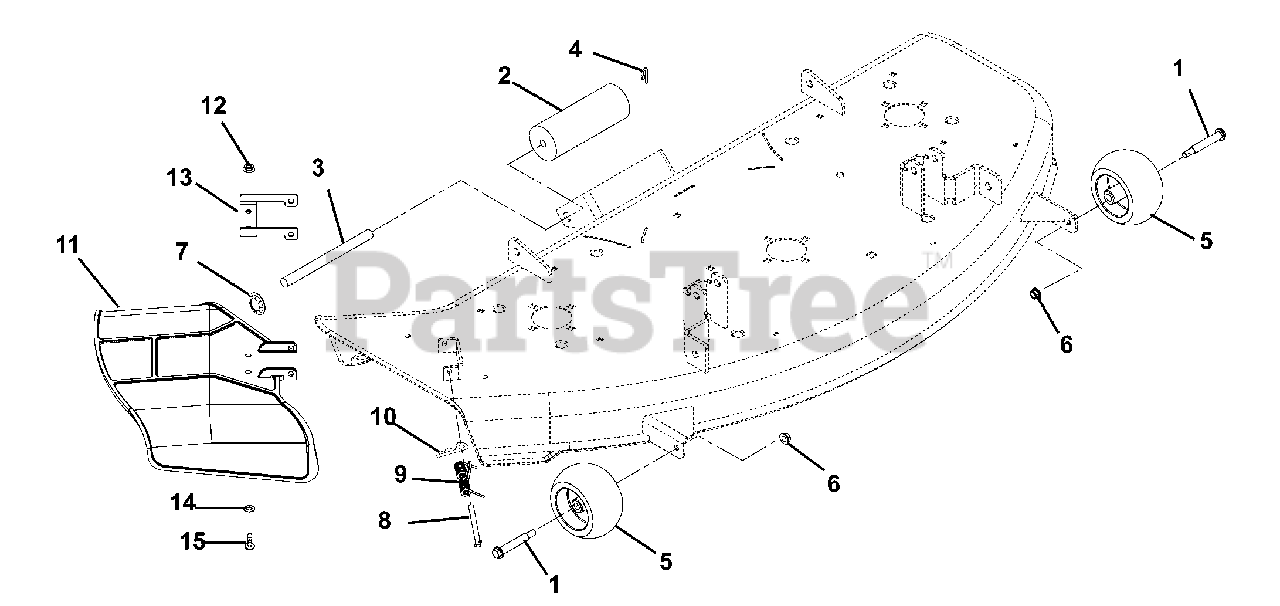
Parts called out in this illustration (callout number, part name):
1	Bolt, Shoulder .38-16 x 2.50 Hex Washer Head Grade 5
2	Roller (094, 096)
3	Pin, Roller (094, 096)
4	Pin, Spring Clip (094, 096)
5	Wheel 5 x 3
6	Nut, Locking-Top-Flange .38-16
7	Push Nut, .625 Shaft (094, 096)
8	Clevis Pin
9	Spring, Torsion
10	Pin, Hair .08 x .18 x 1.18
11	Plastic Chute
12	Nut, Locking, Top Flange .31-18
13	Chute Reinforcement
14	Washer, Flat Steel .38 x .875 x .083
15	Screw, Socket Head, Button Head .31-18 x .75
